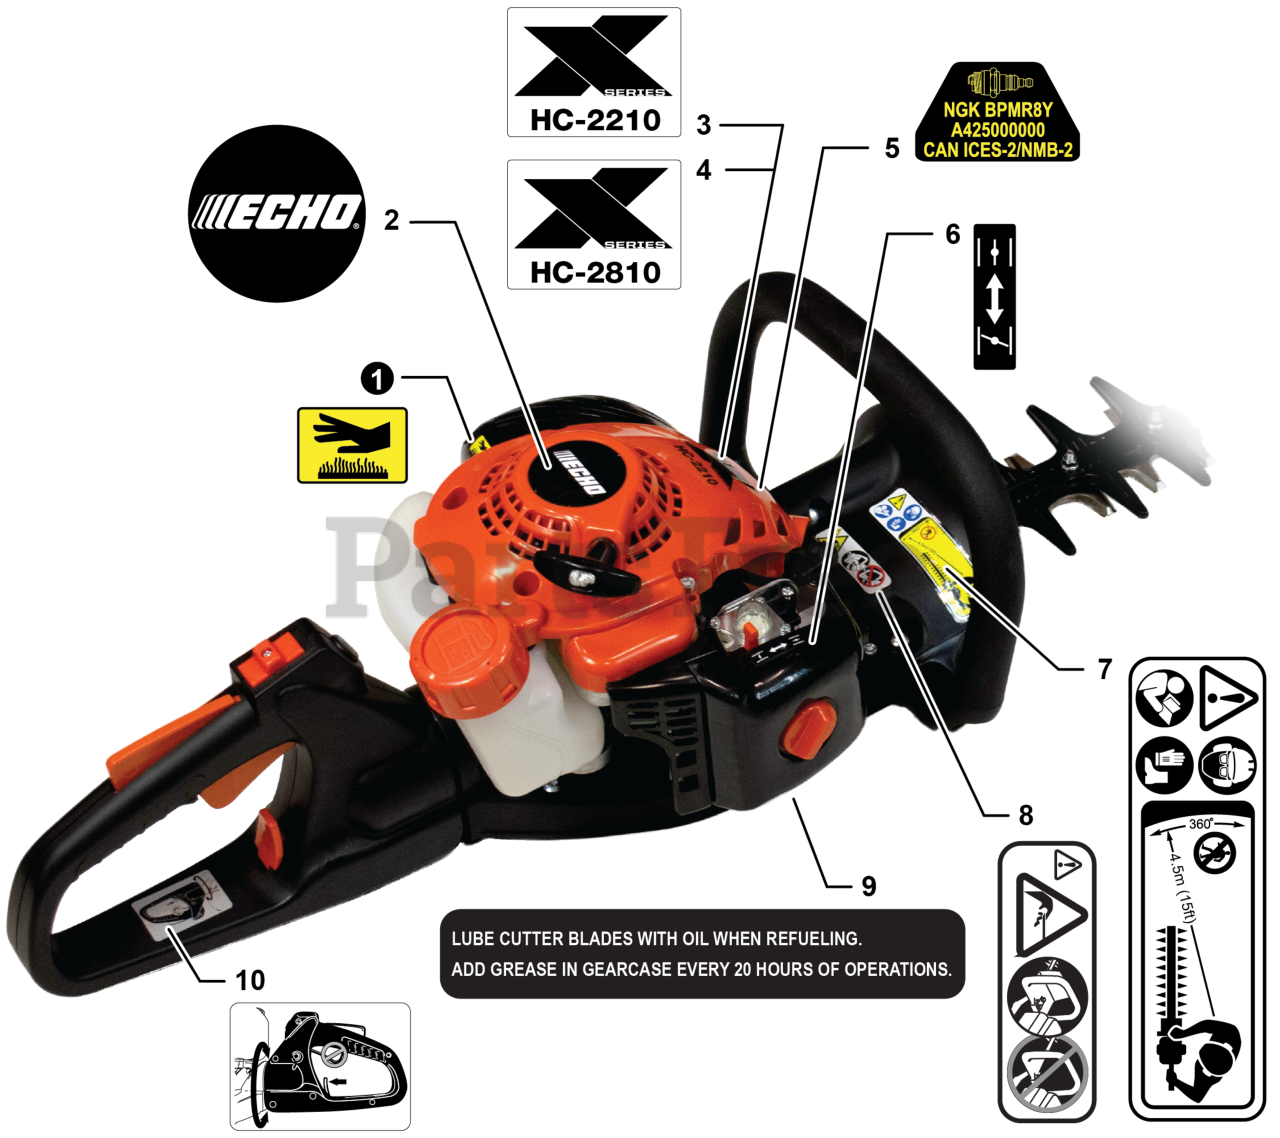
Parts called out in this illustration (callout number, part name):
1	LABEL - CAUTION - HOT
2	LABEL - STARTER - ECHO
3	LABEL - MODEL - HC-2210
4	LABEL - MODEL - HC-2810
5	LABEL - SPARK PLUG - BPMR8Y
6	LABEL - CHOKE
7	LABEL - CAUTION - ISO
8	LABEL - CAUTION
9	LABEL - LUBE BLADES
10	LABEL - CAUTION
